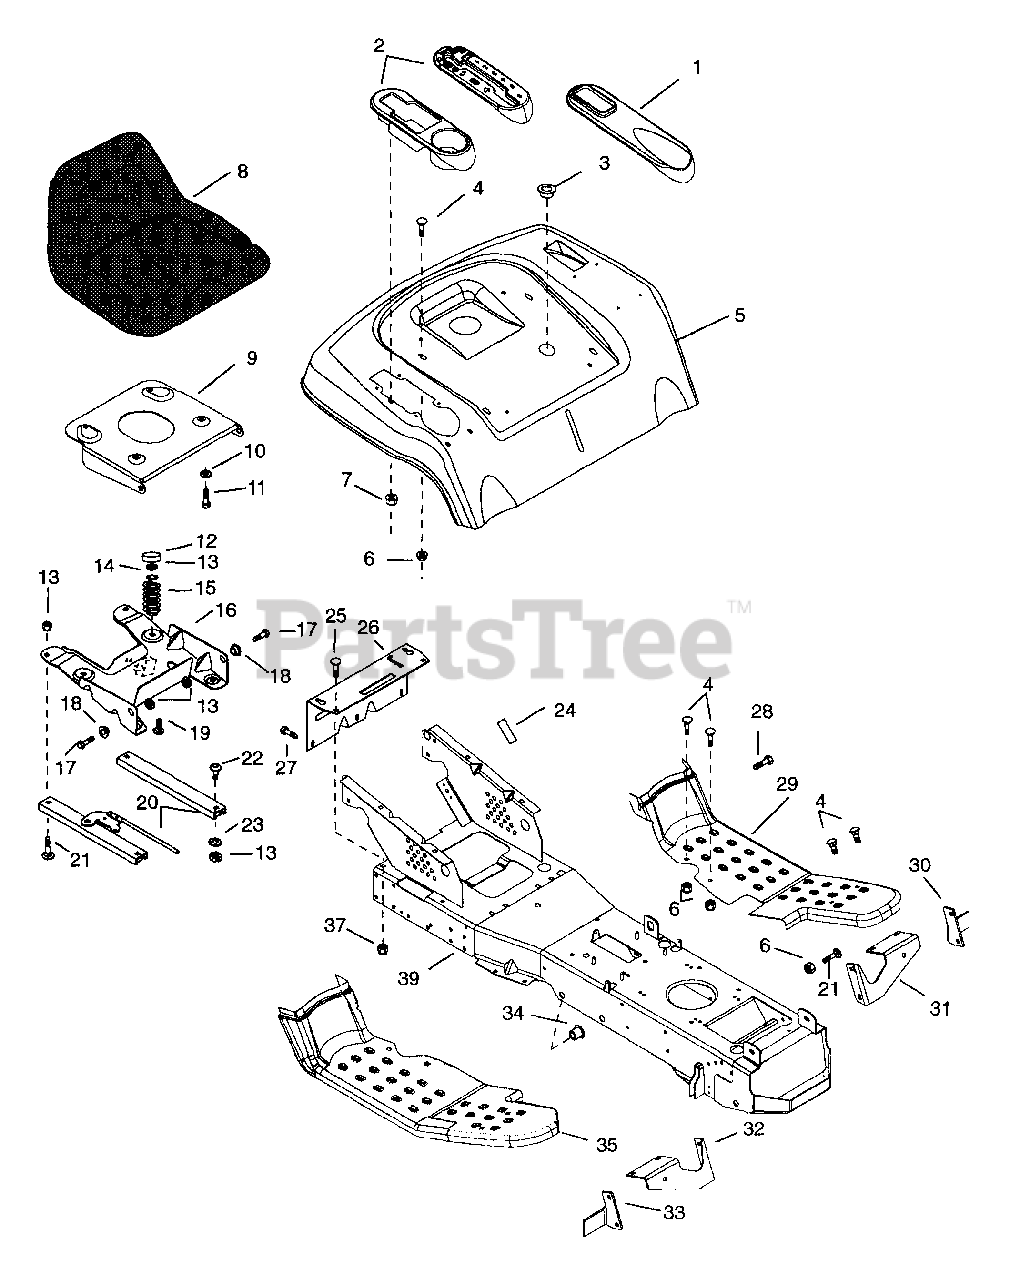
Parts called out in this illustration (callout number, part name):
1	INSERT- LIFT
2	INSERT- SHIFT
2	INSERT - BEVERAGE
3	SNAP BUSHING
4	BLT-RDHDSQNK .312-18X.62SHTPL
5	REAR DECK
6	NUT-FLG. .312-18 PL
7	NUT-SELF-THRDNG FITS.25 STUDPL
8	SEAT- V1400
8	SEAT V-1500 HI WELTLESS
9	SEAT PIVOT PLATE
10	WSHR-LK .312X.097 PL HVY
11	BLT-HEX .31-18X.75 PL GR2
12	TUBE CAP
13	NUT-LK .312-18 GR A PL
14	WSHR-FL-STL.344X.688X.065PL
15	SG-COMP .148X1.23X2.41 WLD87
16	BOX, SEAT
17	BLT-HEX .31-18X.75 PL GR5
18	BSHG-FLG .325X.465X.333X.685
19	BLT-RDHDSQNK.31-18X.75GR5SHTPL
20	SEAT SLIDES -(RAME TAK-3010-4)
21	BLT-RDHDSQNK .31-18X.75 SHT PL
22	SCR-CAP BTHD.31-18X.50 GR5 YZ
23	WSHR-FL-STL .328X.875X.062 PL
24	PAD,BATTERY
25	BLT-RDHDSQNK .375-16X.75 GR5PL
26	DRAW BAR
27	SCR-TAP .312-18X.75 HWH PL TR
28	SCR-TAP .375-16X .50 HWH PL TR
29	FOOTREST- LH
30	BRACKET - MOWER HEIGHT L.H.
31	BRACE - FOOT REST L.H.
32	BRACE - FOOT REST R.H.
33	BRACKET - MOWER HEIGHT R.H.
34	BSHG-FLG .515X.750X.745X1.00NY
35	FOOTREST- RH HYDRO
35	FOOTREST- R GEAR
37	NUT-LK-CTR .375-16 GR A PL
39	MAIN FRAME
